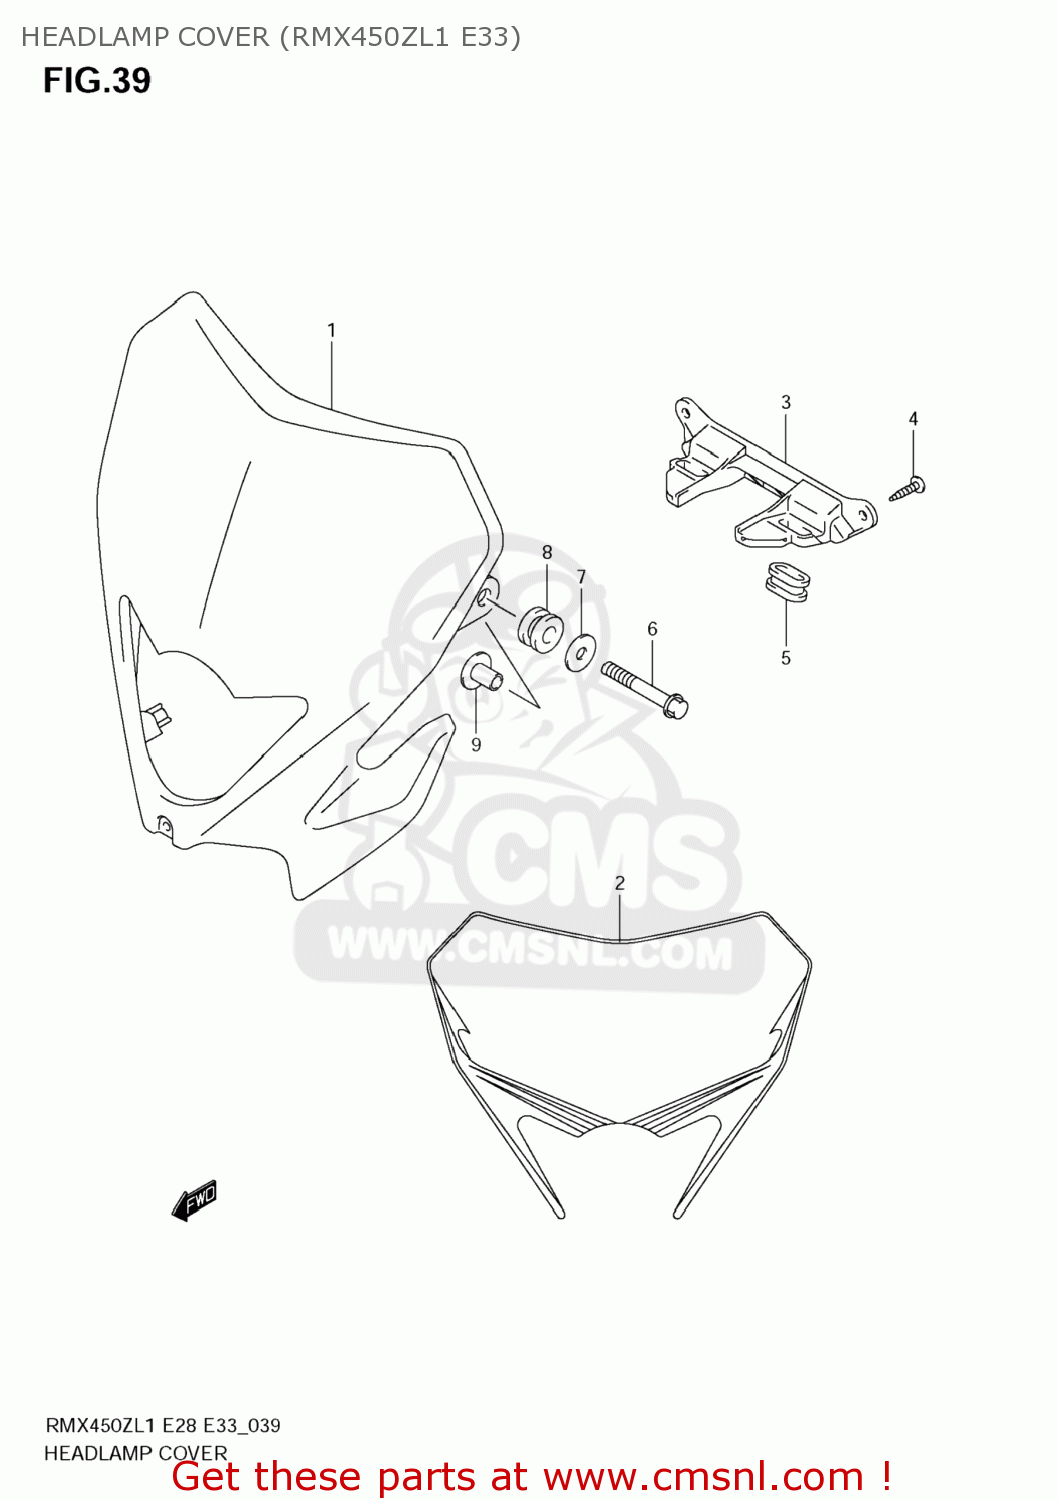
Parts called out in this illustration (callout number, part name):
1	COVER,HEADLAMP
2	TAPE,HEADLAMP COVER
3	COVER,HEADLAMP LWR
4	SCREW
5	CUSHION,HEADLAMP COVER
6	BOLT(6X25)
7	WASHER(6.5X18X1.6)
8	CUSHION
9	WASHER
